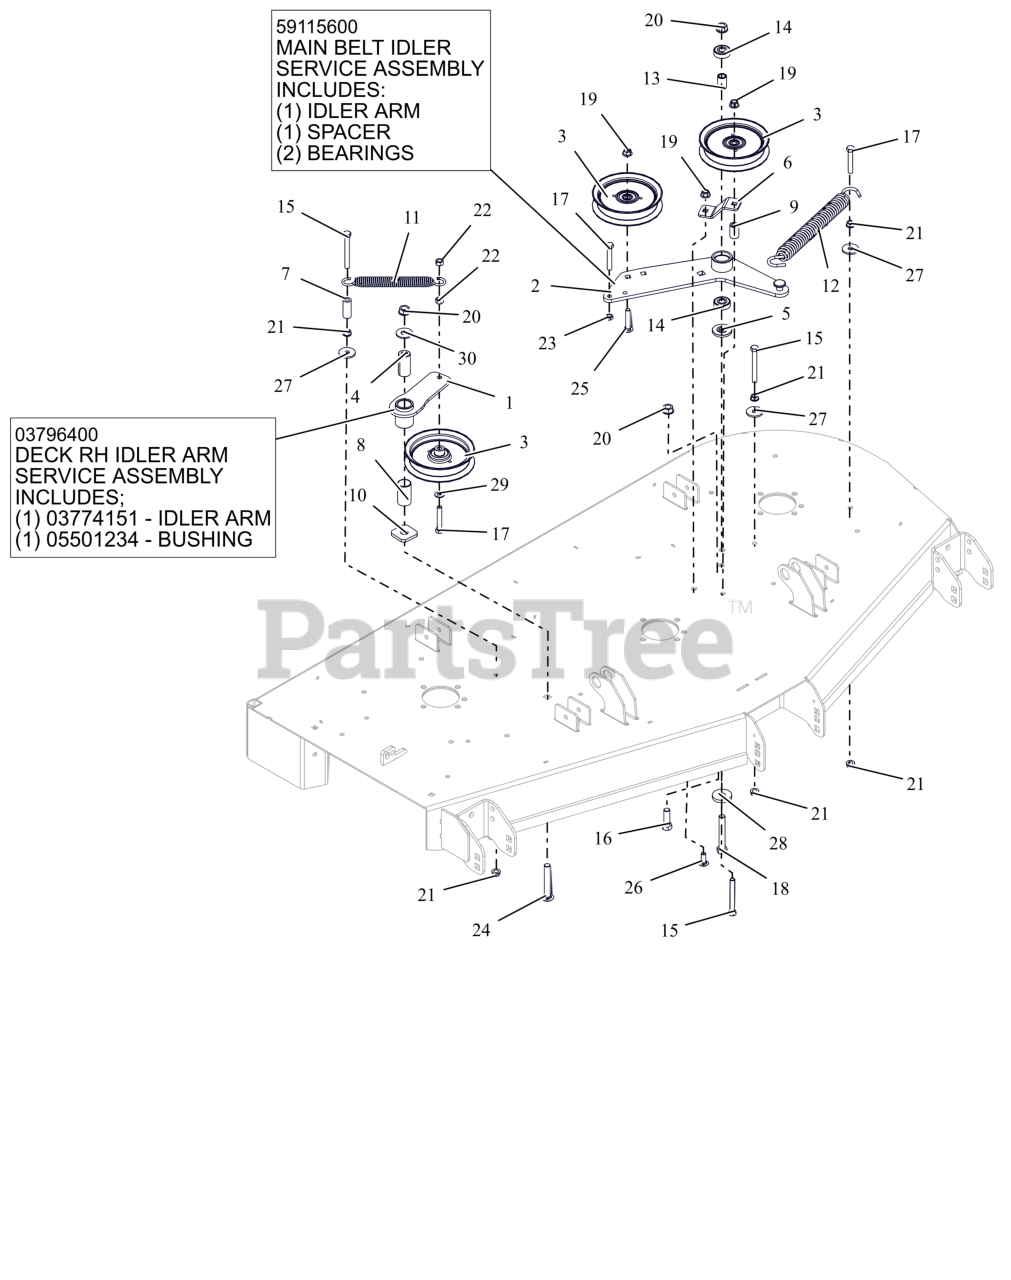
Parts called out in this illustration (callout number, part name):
1	WMT, IDLER ARM - BLACK
1	ASM, IDLER ARM (DECK)
2	WLDMT, DECK PTO IDLR ARM
2	ASSEMBLY, MAIN BELT IDLER
3	IDLER, FLAT 5.00"
4	BSHG, SPCR .502X.997X2.03 PM
5	SPACER, IDLER ARM
6	PTO FIXED IDLER MTG BRKT -RED
7	HOSE, .38 X 1.65
8	BSHG, 1.00X1.125X1.937
9	BUSHING, SLV .380X.750X1.190
10	WSHR-FLT .640X1.75X.250
11	SPRING, EXTENSION
12	SPRING, EXTENSION
13	SPACER .510 X .75 X 1.1485
14	BRG-BALL .500X1.38X.437
15	BLT, HEX .38-16X3.25 G5 ZCC
16	BLT,HEX .50-13X1.50 G5 ZCC
17	BLT,HEX .38-16X2.25 G5 ZCC
18	BLT,HEX .50-13X3.25 G5 ZCC
19	NUT,NYL-FLG .38-16 GF ZCC
20	NUT-LK-CTR-FLG .500-13 GG ZCC
21	NUT, SPNLK-FLG .38-16 G5 ZCC
22	NUT-LK-CTR .38-16 ZC120
23	NUT-JAM .375-16 G2 ZCC
24	BTL,RHSSN .500-13 X 3.25 G5 ZCC
25	BLT,RHSSN.375-16X2.00 G5 ZCC
26	BLT,RHSSN .38-16X1.00 G5 ZCC
27	WSHR,FLT .406X1.375X.135 ZCC
28	WSHR-FL-STL 0.557X1.625X0.25 ZCC
29	WSHR,FLT .406X.812X.065 ZCC
30	WSHR,FLT .563X1.375X.109 ZCC
